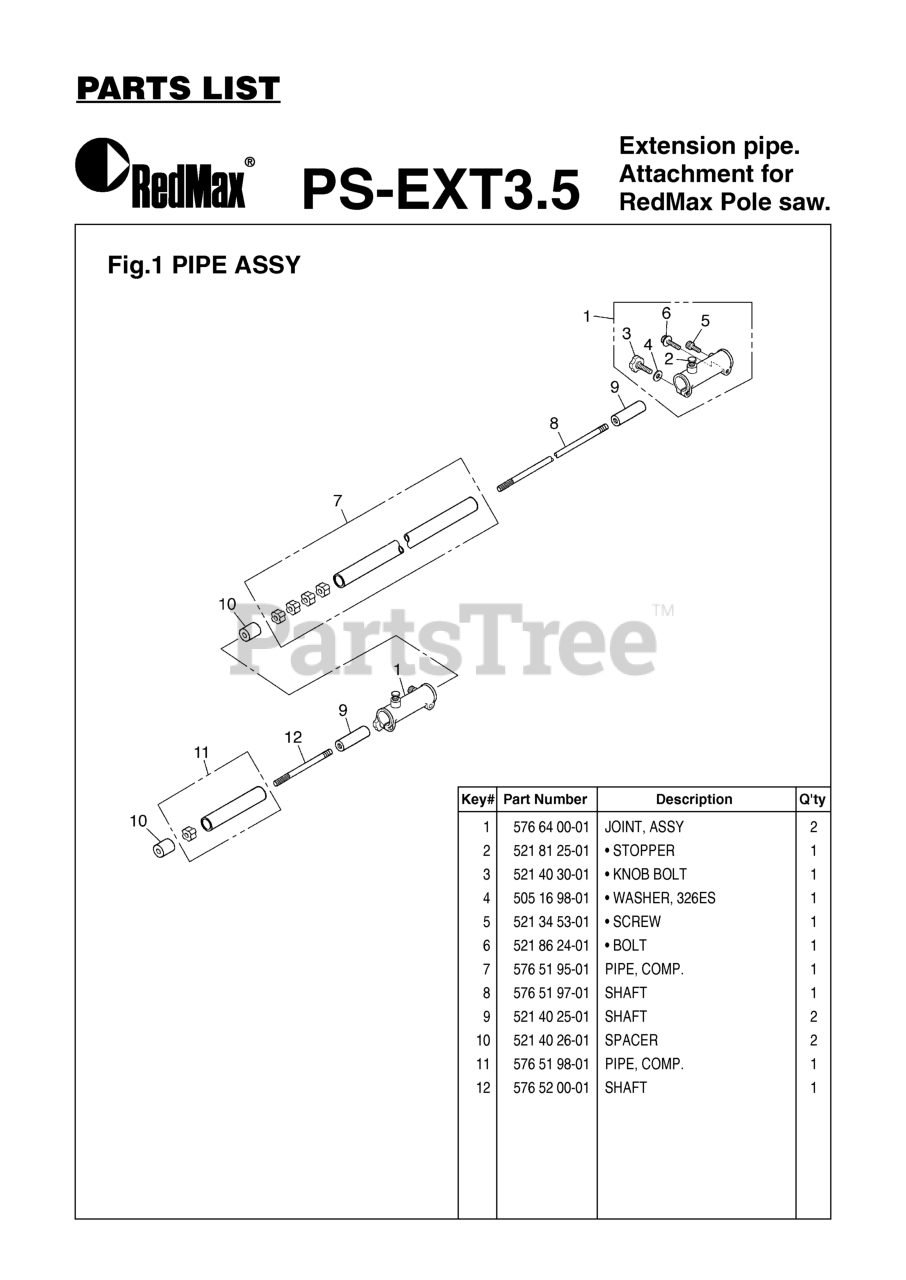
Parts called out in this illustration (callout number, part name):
1	JOINT ASSY
2	STOPPER COMPLETE
3	BOLT, KNOB
4	WASHER,M8x2.3(RP
5	BOLT
6	BOLT,TORX
7	PIPE COMP
9	JOINT, SHAFT (RP
10	SPACER
11	PIPE COMP
